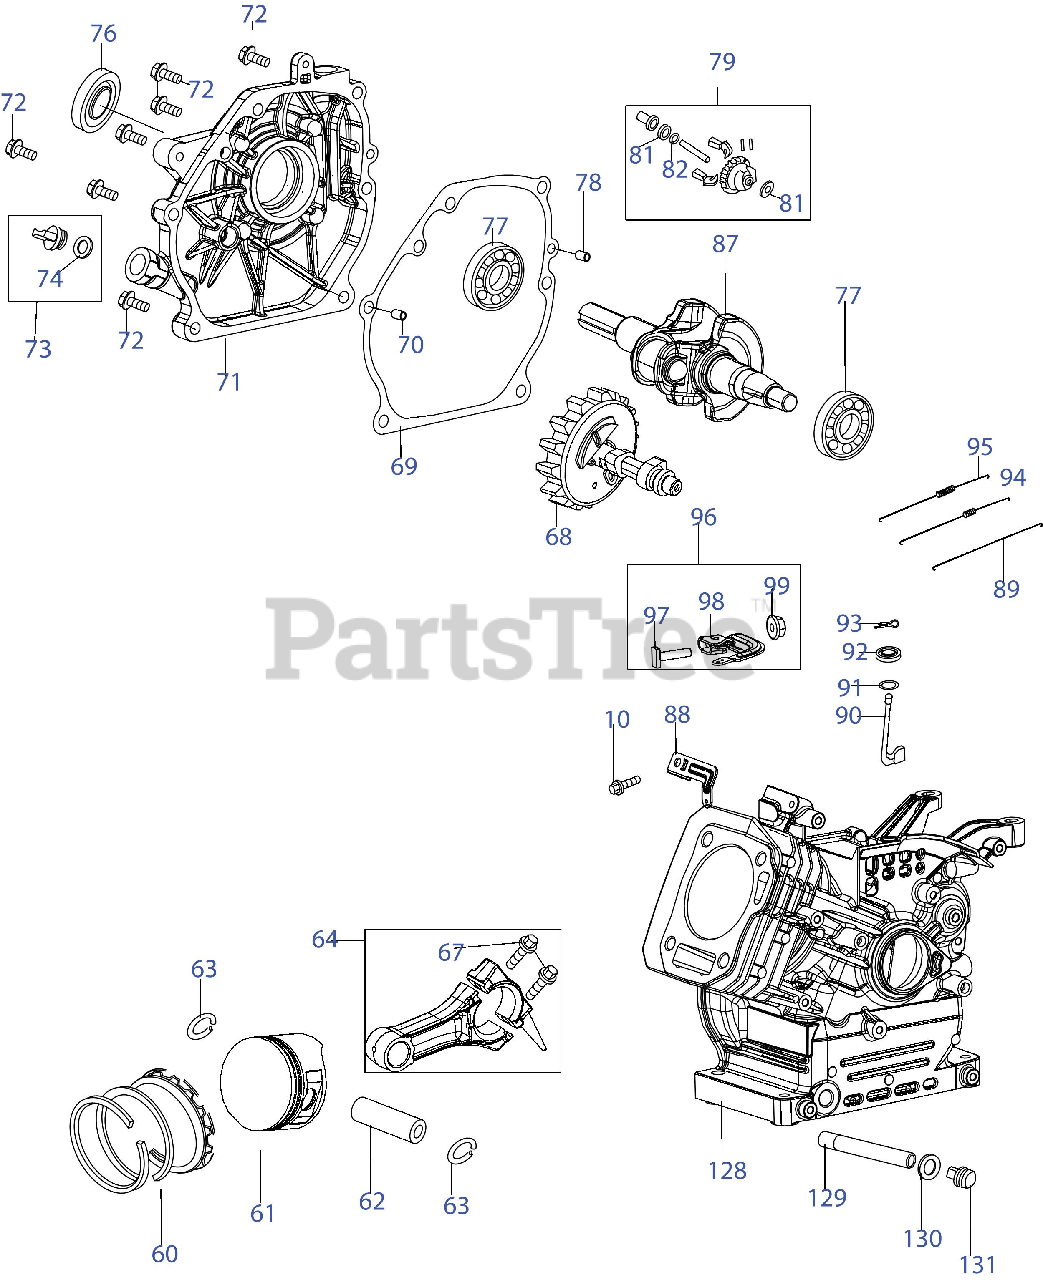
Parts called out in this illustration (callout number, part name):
10	Bolt M6x12
60	Piston Ring Set
61	Piston
62	Wrist Pin
63	Circlip
64	Connecting Rod
67	Connecting Rod Bolt
68	Camshaft
69	Gasket, Crankcase Cover
70	Dowel Pin 9x14
71	Crankcase Cover
72	Bolt M8x32
73	Oil Plug
74	O-Ring 15.8x2.5
76	Oil Seal 25x41.25x6
77	Bearing Tm6205/P63
78	Dowel Pin 7x14
79	Gear Governor
81	Washer 6.2x0.6x15
82	Retaining Rings, Governor Shaft
87	Crankshaft
88	Spring Bracket
89	Rod Governor
90	Shaft,Governor Arm
91	O-Ring 5.2x1.9
92	Oil Seal 6x11x4
93	Cotter Pin
94	Idle Spring
95	Governor Spring
96	Governor Lever
97	Bolt M6x21
98	Governor Lever
99	Flange Nut M6
128	Crankcase
129	Oil Drain Pipe
130	Washer 10x1.5x16
131	Washer,Drain Bolt(M10x1.25x15)
